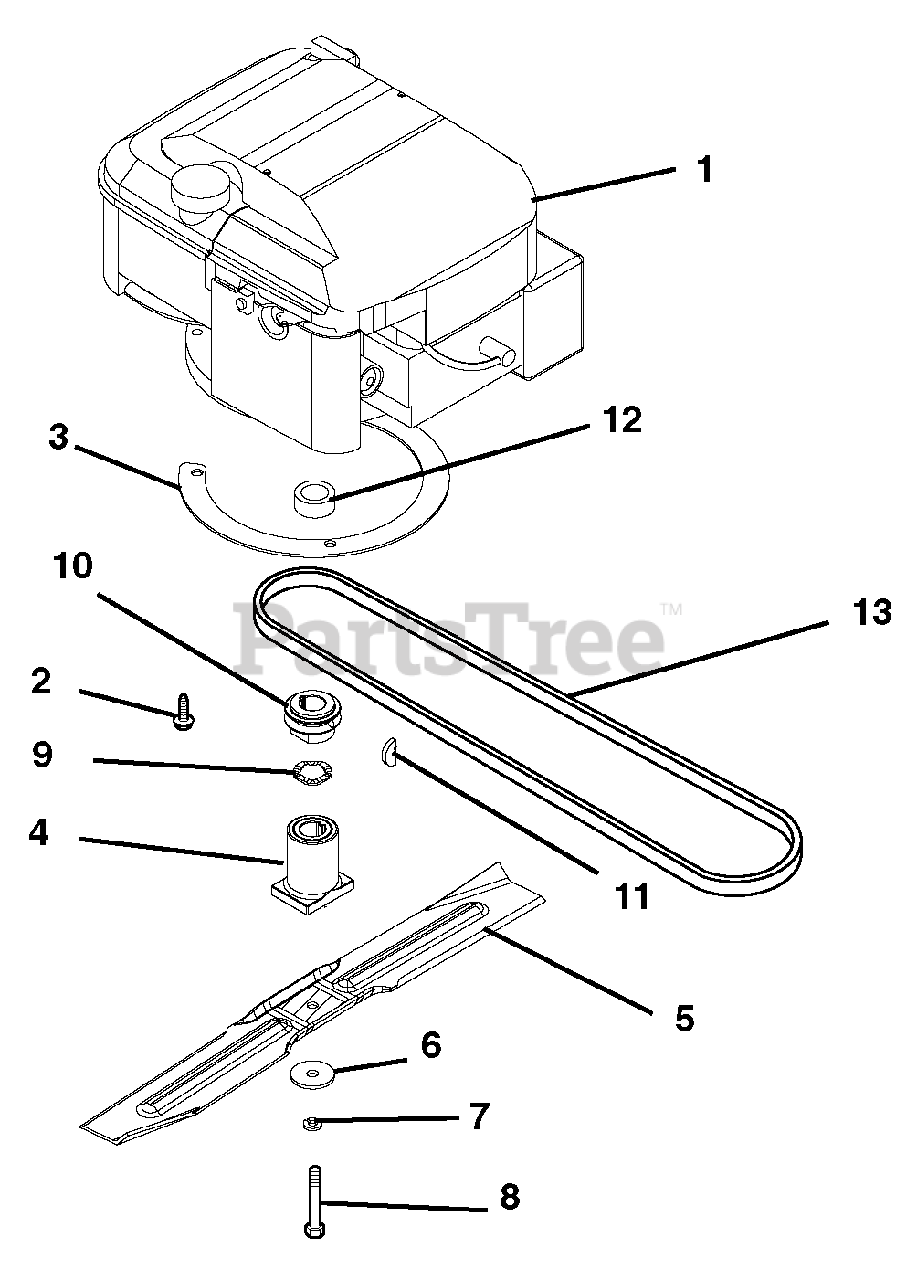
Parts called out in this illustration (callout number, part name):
1	ENGINE, B&S QUANTUM 6.5HP
1	ENGINE, HONDA GCV
1	ENGINE, HONDA GCV EL START
2	@SCR-TAP .38-16X1.00 HWH TR YZ
3	RING, ENGINE BOLT
4	ADAPTER, BLADE HUB
4	ADAPTER, 1" HONDA CRANK BLADE
5	21" MOWER BLADE
6	WSHR-FL-STL .390X1.5X.125 YWZC
7	@WSHR-LK .38X.094 REG YWZC
8	BOLT, 3/8-24X2.5 G8
8	SUPPORT, TRANSAXLE
9	WASHER-WAVE .885X1.311X.125
9	WASHER - WAVE 1.09X1.37X.016
10	PULLEY-SINTERED IRON LM
10	PULLEY, 1" HONDA CRANK DRIVE
11	KEY-WDRF .156X.625X.25 SAE 6
11	KEY-WDRF .188X.625X.25 SAE 61
12	SPACER, .875X1.125X.551
12	SPACER, HONDA ELEC START CRANK
13	V-BELT, 3L-WRAPPED
